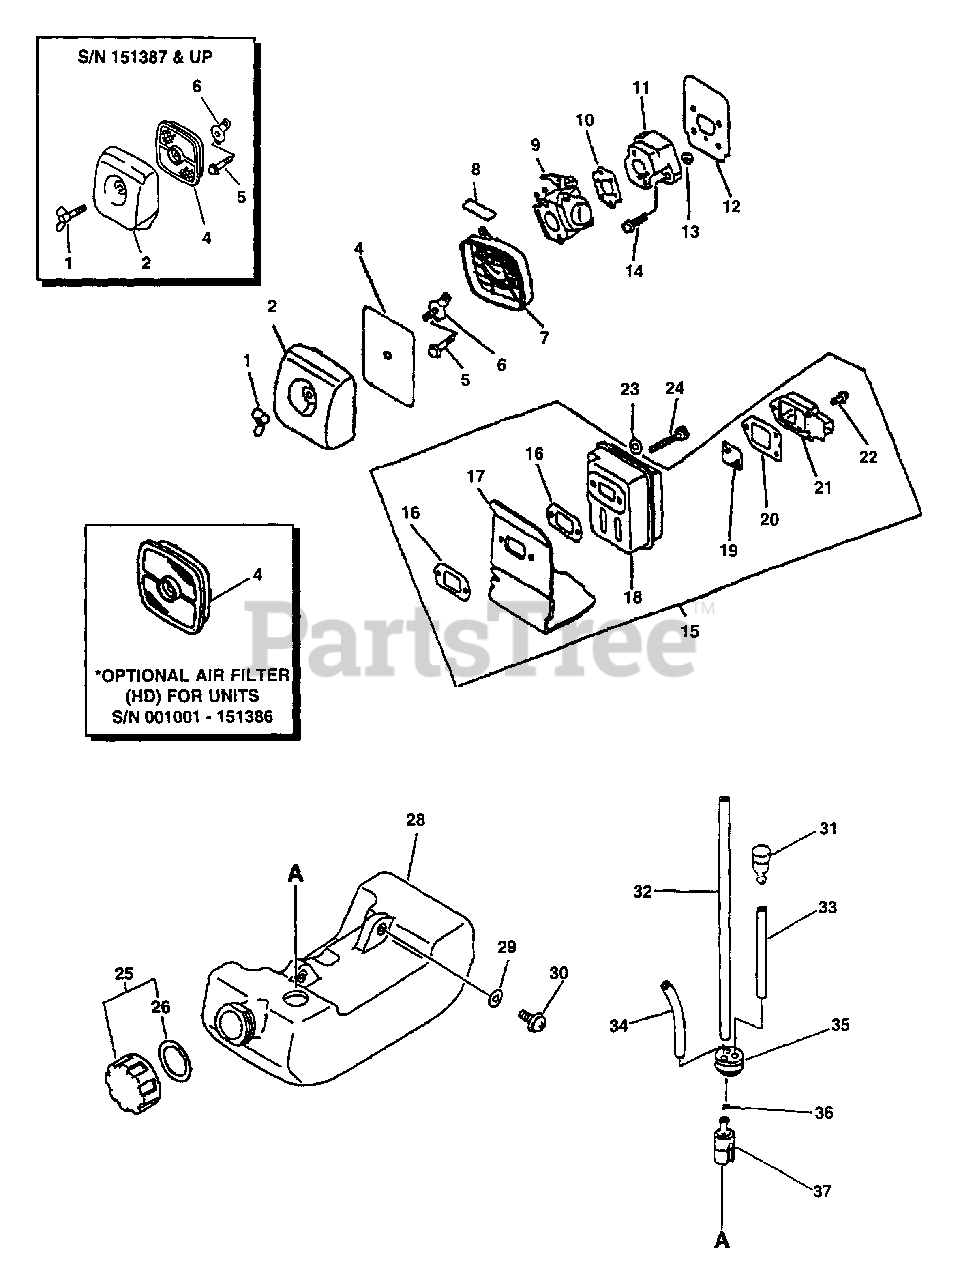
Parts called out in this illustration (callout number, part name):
1	WINGNUT - 6
1	BOLT, WING 5×20
2	COVER, AIR FILTER
2	COVER, AIR FILTER - GRAY
4	FILTER, AIR
4	FILTER, AIR - SINGLE LAYER
5	SCREW 5×65
6	PLATE, PREVENT
7	AIR FILTER CASE ASSY
8	LABEL, CHOKE
9	CARBURETOR - C1U-K29
9	CARBURETOR - C1U-K47
10	GASKET, INTAKE
11	INSULATOR, INTAKE
12	HEAT SHIELD, INTAKE
13	NUT M5
14	SCREW 5×20
15	MUFFLER ASSY
16	GASKET, EXHAUST
17	COVER, EXHAUST
19	SCREEN, SPARK ARRESTER
20	GASKET, EXHAUST
21	GUIDE, EXHAUST - INNER
22	SCREW 4×10
23	WASHER, FLAT 5.5×10×0.8
24	BOLT 5×55
25	CAP ASSY, FUEL
26	GASKET, FUEL CAP
28	TANK, FUEL
29	WASHER 5.5×12×0.8
30	SCREW 5×16
31	VENT ASSY
32	PIPE, FUEL 3x-5x-180
33	PIPE, FUEL 3x-5x-70 BLACK
34	PIPE, FUEL 3×6×80 CLEAR
35	GROMMET, FUEL
36	CLIP 6 MM
37	FILTER, FUEL
